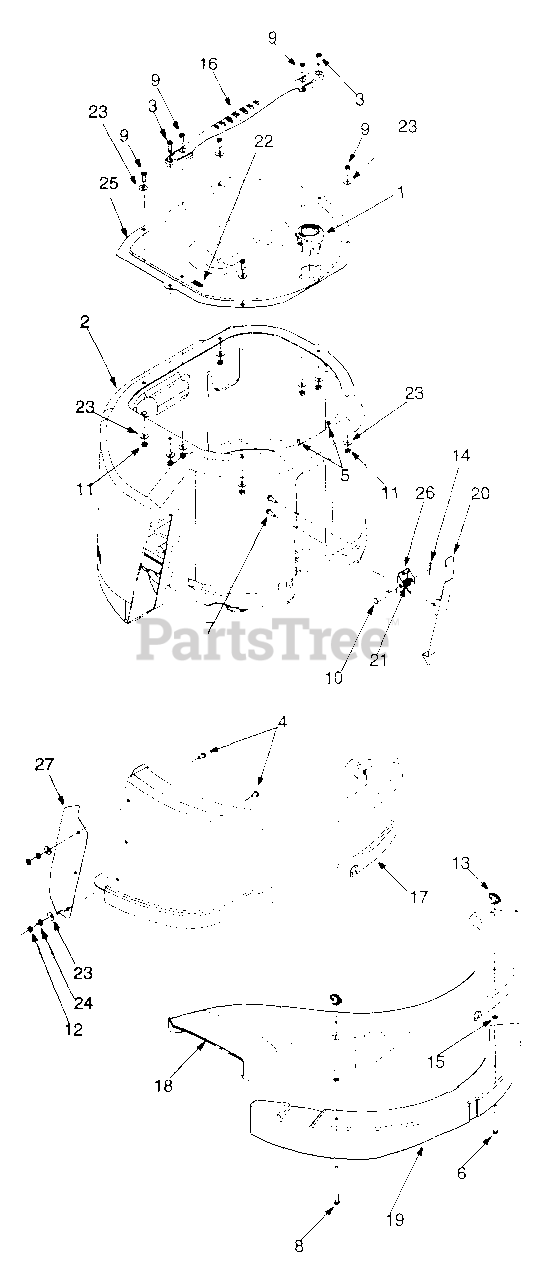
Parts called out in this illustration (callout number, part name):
1	Flow Indicator Assembly
2	Grass Bag Assembly
3	Machine Screw 1/4-20 x 1.0
4	Machine Screw 1/4-20 x 0.5"
5	Hex Screw #10-16 x 0.5"
6	Hex Screw 1/4-20 x 2.75"
7	Self-Tapping Screw 1/4-20 x 0.75"
8	Hex Screw 1/4-20 x 3.75"
9	Machine Screw 1/4-20 x 0.75"
10	Clevis Pin
11	Hex Sems Nut 1/4-20
12	Jam Nut
13	Wing Nut
14	Cotter Pin
15	Speed Nut
16	Bag Handle
17	Discharge Chute: Grass Bag
18	Side-Discharge Chute
19	Mulching Plug
20	Bag Release Lever
21	Torsion Spring
22	Clip Spring
23	Flat Washer
24	Lock Washer
